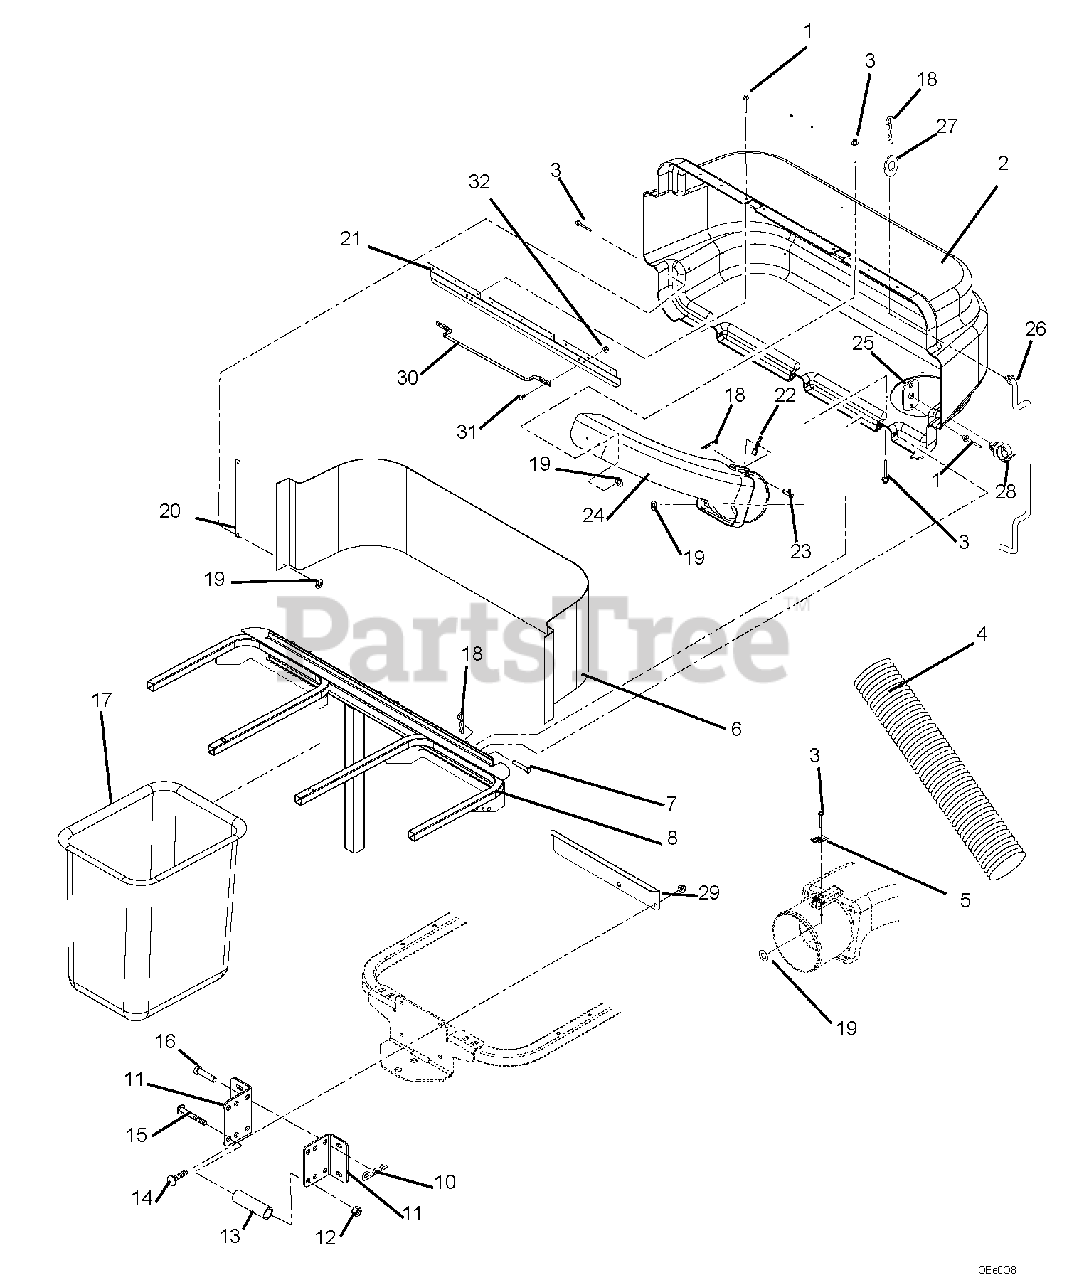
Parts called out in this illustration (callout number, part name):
1	Rivet, Pop .187 x .402
2	Cover, Bagger with Decal
3	Rivet, Pop .187 x .375
4	Hose 7 x 45
5	Thumb Latch
6	Screen, Bagger
7	Pin, Clevis .368/.373 x 3.25
8	Weldment, Bagger Frame
9	Nut, Locking-Top-Flange .38-16
10	Pin, Hair-External .12 x .31 x 2.37
11	Bracket, Bagger Mount
12	Nut, Locking-Top-Flange .50-13
13	Spacer, Pivot
14	Bolt, Round Head Square Neck .38-16 x 1.25 Grade 5
15	Bolt, Hex .50-13 x 3.00 Grade 5
16	Pin, Clevis .494 x 2.50
17	Grass Bagger Basket
18	Pin, Hair
19	Washer, Flat-Steel .219 x .50 x .049
20	Strap, Cover
21	Latch, Cover
22	Indicator, Flow
23	Pin, Clevis .31 x 2.62 Grade 5
24	Boot, Upper
25	Plate, Rod Clip
26	Prop, Rod, Bagger
27	Washer, Flat-Steel .046 x .812 x .065
28	Clip .38
29	Deflector, Exhaust
30	Bagger Handle
31	Bolt, Round Head Square Neck .25-20 x .75 Grade 5
32	Nut, Locking Top Flange .25-20
